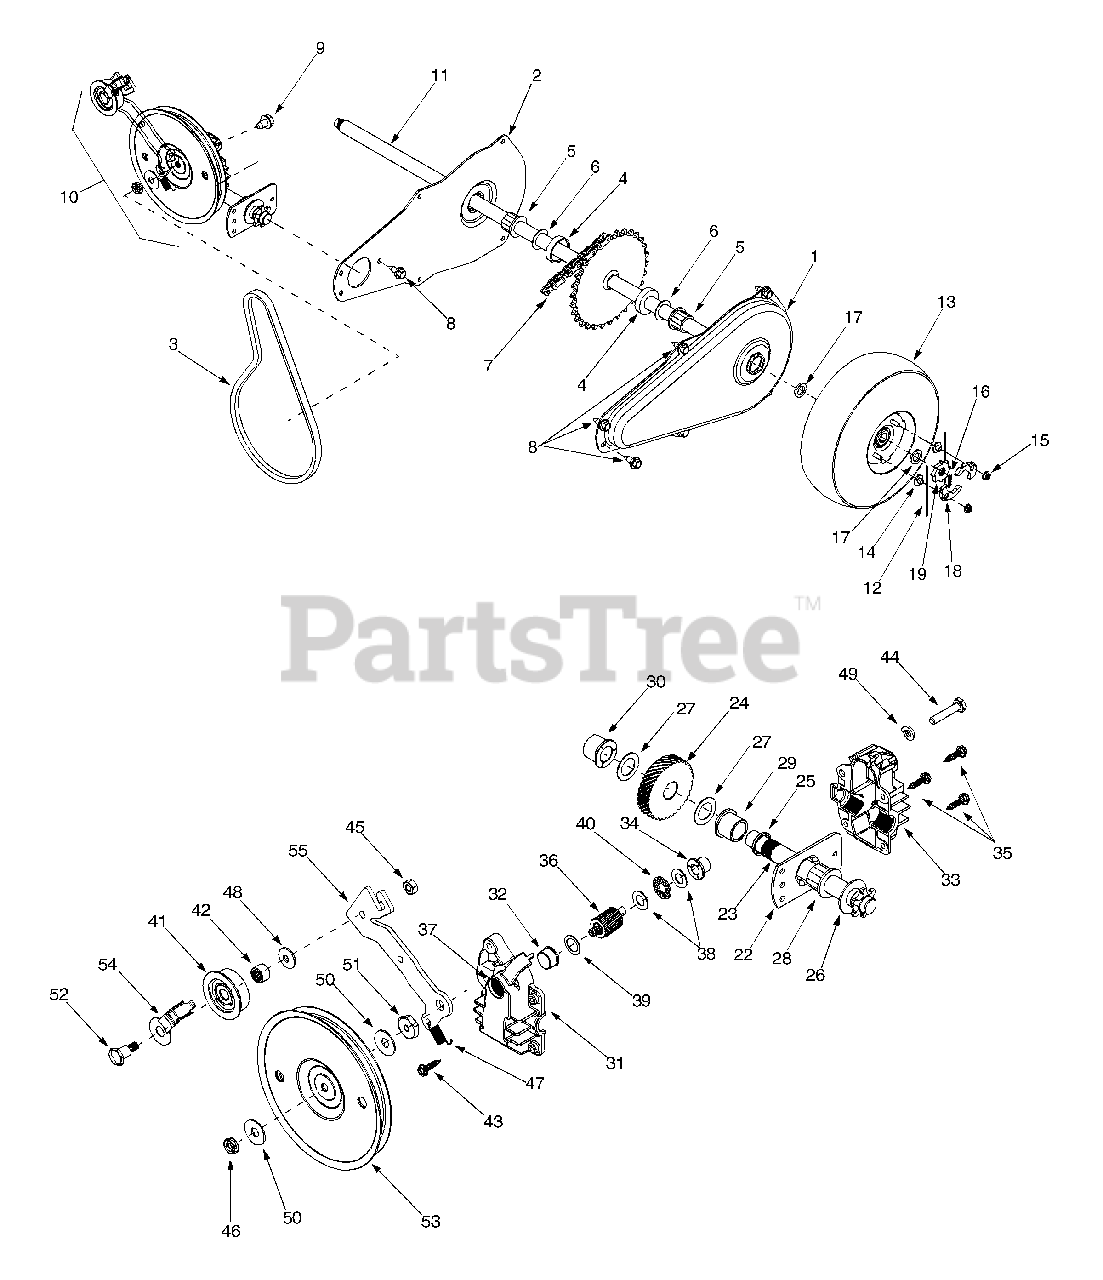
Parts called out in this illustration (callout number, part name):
3	V-Belt
4	Spacer
5	Hex Flange Bearing
6	Flat Washer
7	Chain
8	Hex Washer Screw 1/4-14
9	Hex Washer Screw 5/16
10	Transmission Assembly
11	Axle Assembly
12	Plastic Spring Ratchet
13	Wheel Complete 10 x 4 x 4
14	Hex Nut 1/4-20
15	Hex Flanged Lock Nut 1/4-20
16	Cotter Pin
17	Flat Washer 5/8 ID x 1.0 OD
18	Pawl LH .345 ID
19	Wheel Ratchet 1.62 OD x .5 serr
23	Output Shaft 6T Sprocket
24	Helical 34T Gear
25	Oil Seal
26	Flat Washer .64 ID x 1.24 OD
27	Flat Washer 5/8 x 1.0
28	Hex Flange Bearing .631 ID
29	Flange Bearing .629 ID
30	Flange Bearing .566 ID
31	Lower Housing
32	Flange Bearing .503 ID
33	Upper Housing
34	Flange Bearing .378 ID
35	Hex Washer Screw #10-16 x .75
36	Pinion Shaft 10T
37	Oil Seal
38	Thrust Washer .382 ID x .684 OD
39	Flat Washer .504 ID x .70 OD
40	Thrust Bearing .375 ID x .812 OD
41	Pulley Ass'y Idler w/ Bearing
42	Needle Bearing .375 ID x .375 OD
43	Hex Screw #10-16 x .75
44	Hex Cap Screw 1/4-20 x 1.25
45	Hex Nut 1/4-28
46	Hex Jam Nut 5/16-24 LH Thd
47	Extension Spring 1.12 Lg
48	Bell Washer .265 ID x .75 OD
49	Lock Washer 1/4
50	Bell Washer .325 ID x .930 OD
51	Shoulder Spacer .375 ID x .165 OD
52	Shoulder Bolt 1/4-28 x .375
53	Flat Pulley 5.06 Dia
54	Belt Keeper
55	Idler Bracket
